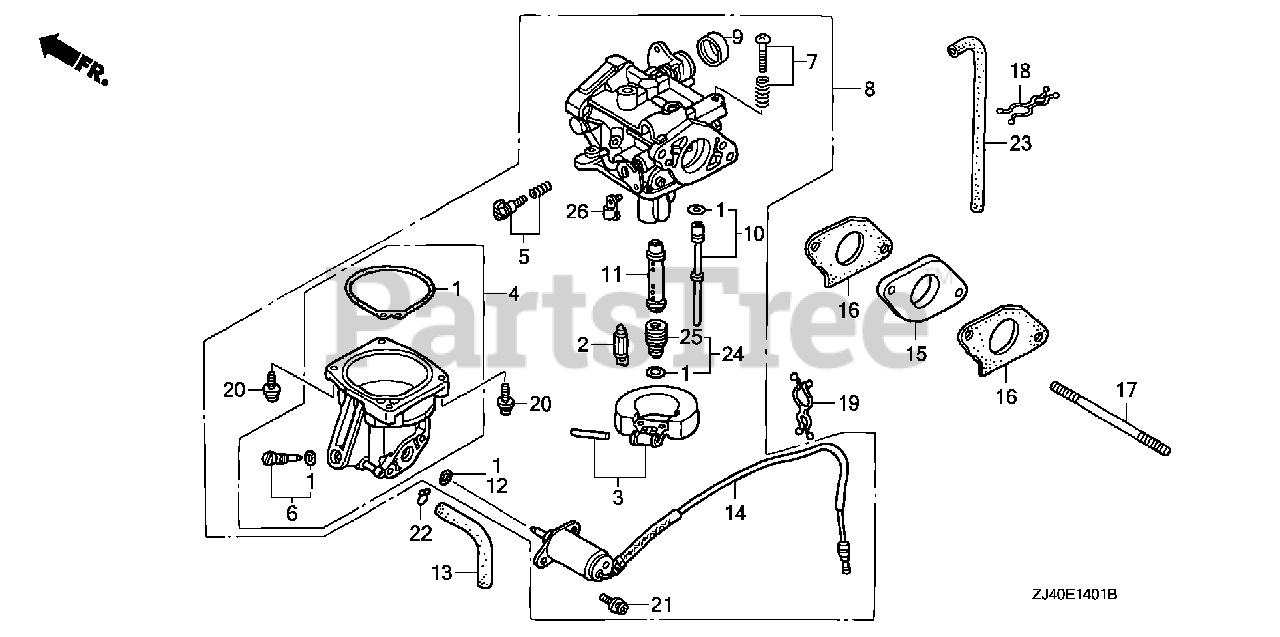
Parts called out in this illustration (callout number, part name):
1	GASKET SET
2	VALVE SET, FLOAT
4	CHAMBER SET, FLOAT
6	SCREW SET, DRAIN
8	CARBURETOR ASSY. (BG26B A)
8	CARBURETOR ASSY. (BG26B B)
9	CAP, CHOKE DUST
10	JET SET (#42)
11	NOZZLE, MAIN
12	O-RING (5.8X1.9)
13	TUBE, DRAIN
14	VALVE ASSY., SOLENOID
15	INSULATOR, CARBURETOR
16	GASKET, CARBURETOR
17	BOLT, STUD (6X100)
18	CLIP, WIRE HARNESS
19	CLIP, PURSE LOCK
20	SCREW-WASHER (4X14)
21	SCREW-WASHER (5X12)
22	CLIP, TUBE (B8)
23	BULK HOSE, VACUUM (4.5X1000) (4.5X540)
24	JET SET, MAIN (#110)
24	JET SET, MAIN (#112)
24	JET SET, MAIN (#115)
26	ARM, THROTTLE LINKAGE
